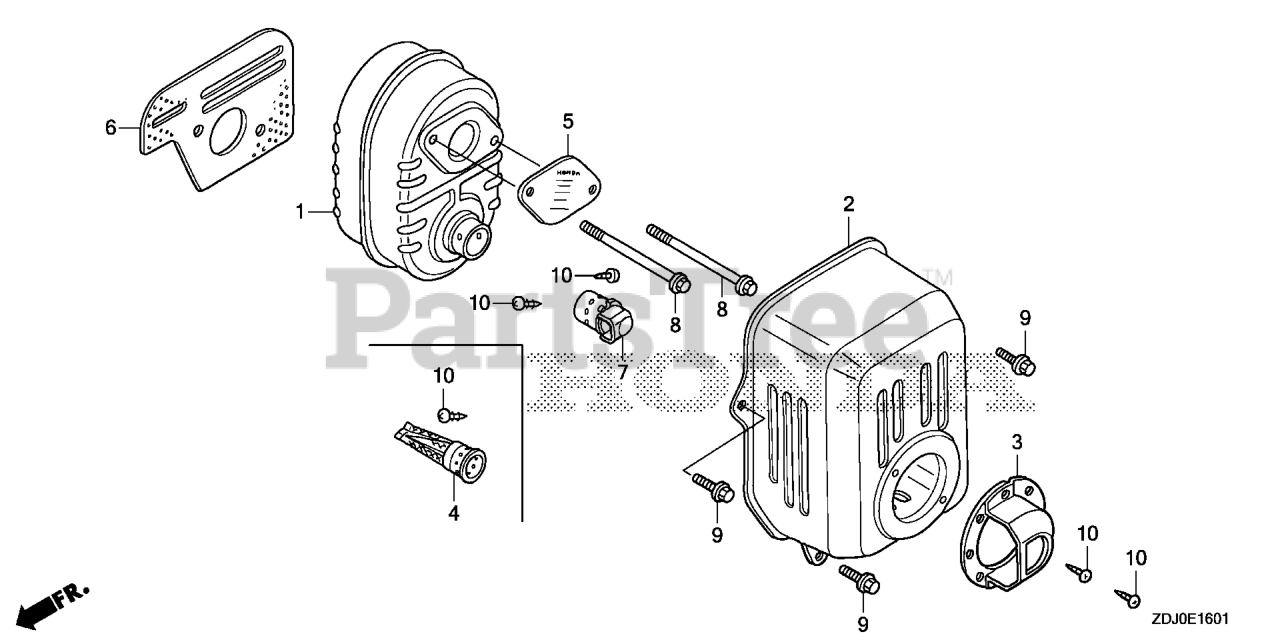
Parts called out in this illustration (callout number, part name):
2	PROTECTOR, MUFFLER
3	CAP, MUFFLER (TO 1207644)
4	ARRESTER, SPARK (TO 1207644)
5	PLATE, ARRESTER NUMBER (TO INSTALL OPTIONAL SPARK ARRESTER)
6	GASKET, MUFFLER
7	DEFLECTOR, MUFFLER (TO 1207644)
8	BOLT, FLANGE (6X79) (CT200)
9	BOLT, FLANGE (6X14)
10	SCREW, TAPPING (4X6) (TO INSTALL OPTIONAL SPARK ARRESTER)
